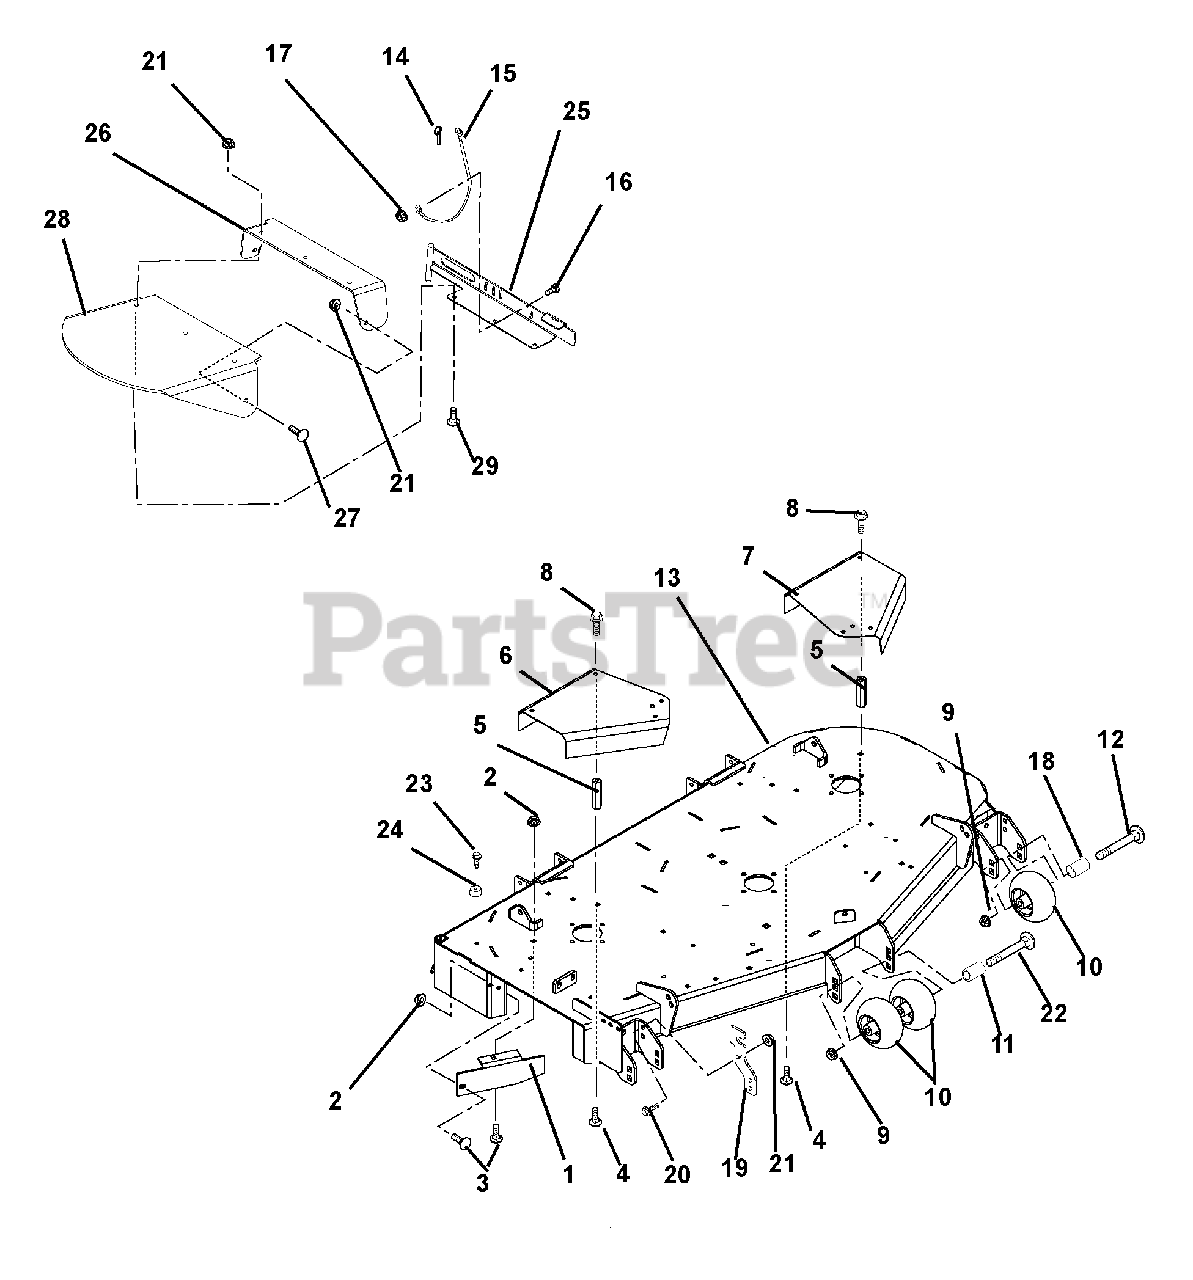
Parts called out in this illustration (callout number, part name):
1	52-in. Rear Discharge Baffle
1	60-in. Rear Discharge Baffle
1	72-in. Rear Discharge Baffle
2	Nut, .31-18 Nyloc Flange
3	Bolt, Round Head Square Neck .31-18 x 1.00 Grade 5
4	Bolt, Round Head Square Neck .31-18 x .75 Loctite with Epoxy Patch
5	Nut, Coupling .31-18 x 3.00
6	52-in. Right Hand Spindle Guard (Serial Number 000699 and Below)
6	60-in. Right Hand Spindle Guard
6	72-in. Right Hand Spindle Guard
7	52-in. Left Hand Spindle Guard
7	60-in. Left Hand Spindle Guard
7	72-in. Left Hand Spindle Guard
8	Bolt, SEMS .31-18 x .62
9	Nut .50-13 Nyloc Flange
10	Anti-Scalp Wheel
12	Bolt-Round Head Square Neck .50-13X5.00
13	52-in. Mower Deck
13	60-in. Mower Deck
13	72-in. Mower Deck
14	Pin, Spring Ball .375 OD x 1.50
15	Cable, Hood
16	Bolt, Hex .25-20 x .75 Grade 5
17	Nut, Locking Top Flange .25-20
18	Spacer, .510 x .625 x 3.35
19	Chute, Storage Bracket
20	Bolt, Hex .38-16 x 1.00
21	Nut, .38-16 Nyloc Flange
22	Bolt, Round Head Square Neck .50-13 x 8.50
23	Screw, Tapping .31-18 x .75 Hex Washer Head Thread
24	Bumper, Recessed 1.50 x .63 , .31 Thru Hole
25	52-inch and 60-inch Discarch Chute Mounting Weldment
25	72-inch Discharge Chute Mounting Weldment
26	Rubber Discharge Chute Support
27	Bolt, Round Head Square Neck .38-16 x 1.00 Grade 5
28	Chute, Rubber Discharge
29	Bolt, Round Head Square Neck .38-16 x 1.25 Grade 5
